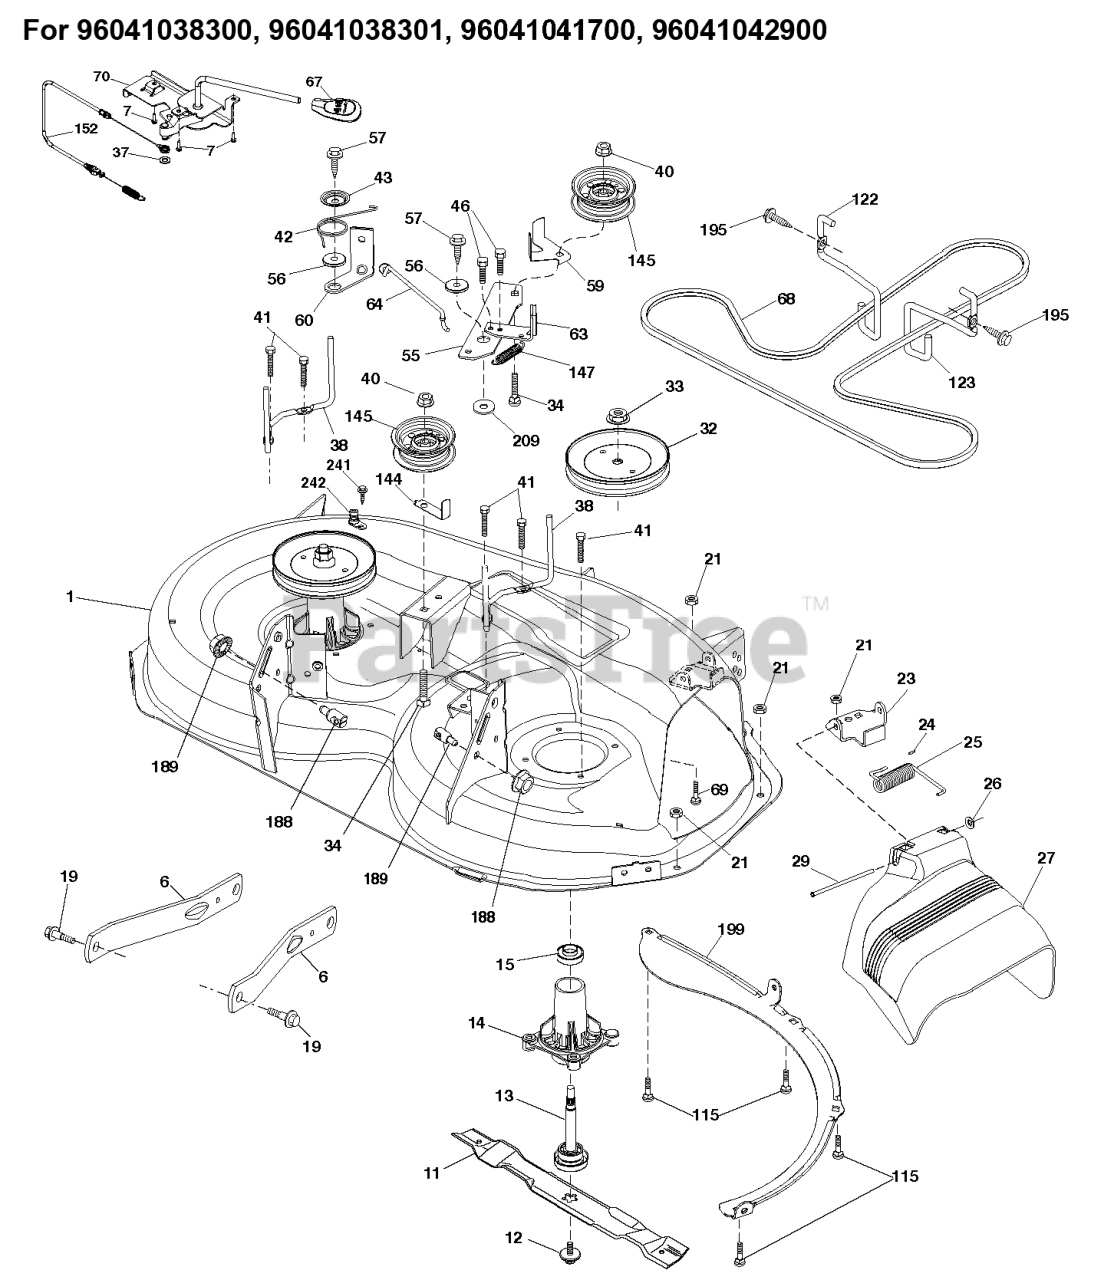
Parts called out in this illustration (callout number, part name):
1	Weldments
1	DECK SVCX1.38"194251X418 KIT
6	ARM.SUSPENSION.MOWER.R
7	SCREW.#10 X 0.750.BOS
7	Screws
11	BLADE.2 IN 1.38"DECK.BLACK
12	SCREW.SEMS.7/16-20X1.HEX.HEAD
13	SHAFT ASM.MNDRL.N/GREASEABLE
14	RP.HOUSING.MANDREL.4PT.
14	KIT.MANDREL.NONGREASE.TALL
15	BEARING.MANDREL.TOP.EXTENDED
19	BOLT.SHOULDER
23	BRKT.DEFLECTOR.38"2005+
24	CAP-SLEEVE LT
25	SPRING.TORSION.DEFLECT
26	NUT PUSH M
27	SHIELD, DEFLECTOR
29	ROD.HINGE
29	Rods
32	PULLEY.MANDREL.5.0.PD.38"
34	GSPW Bolts
34	BOLT.3/8-16X1.50
37	WASHER PLAIN WASHER 3/8 X 0.08
37	WASHER
38	KEEPER BELT LH MANDREL
40	NUT LOCK FLG 3/8-16 UNC
41	BOLT.HEX.WASHR.HED.313-18X1.19
42	SPRING.TORSION.BRAKE
43	SRPING.TORSION.RETAINE
46	SCREW.1/4-20X5/8
56	SPACER.RETAINER
57	SCREW 3/8-16X1
59	GUARD, BELT
60	ARM BRAKE MOWER RH 38"
63	RP ARM.BRAKE.MOWER.38"LH.TEX
64	LINK BRAKE
67	HANDLE.CLUTCH.CABLE.LT
69	Bolts
69	BOLT
70	CLUTCH.ASM.MANUAL.LT.PRED
115	BOLT.CARR.5/16-18X5/8.SHORT
122	KEEPER BELT ENGINE LH
123	KEEPER BELT RH
144	KEEPER BELT
145	PULLEY.IDLER.48"PRIMARY
147	SPRING RETURN
152	CABLE.CLUTCH.MANUAL.
188	STUD.W/"D"ANTI-ROTATION
188	STUD.FASTNER.W/ANTI-ROTATE
189	NUT LOCK HEX FLANGE 5/16-18
189	GSPW Nuts
195	SCREW, 3/8-16X3/4
199	BAFFLE.VORTEX.FRONT.38"
241	SCREW.TT.#10-32X.5.3/8.FLANGE
242	PORT.WASHOUT
